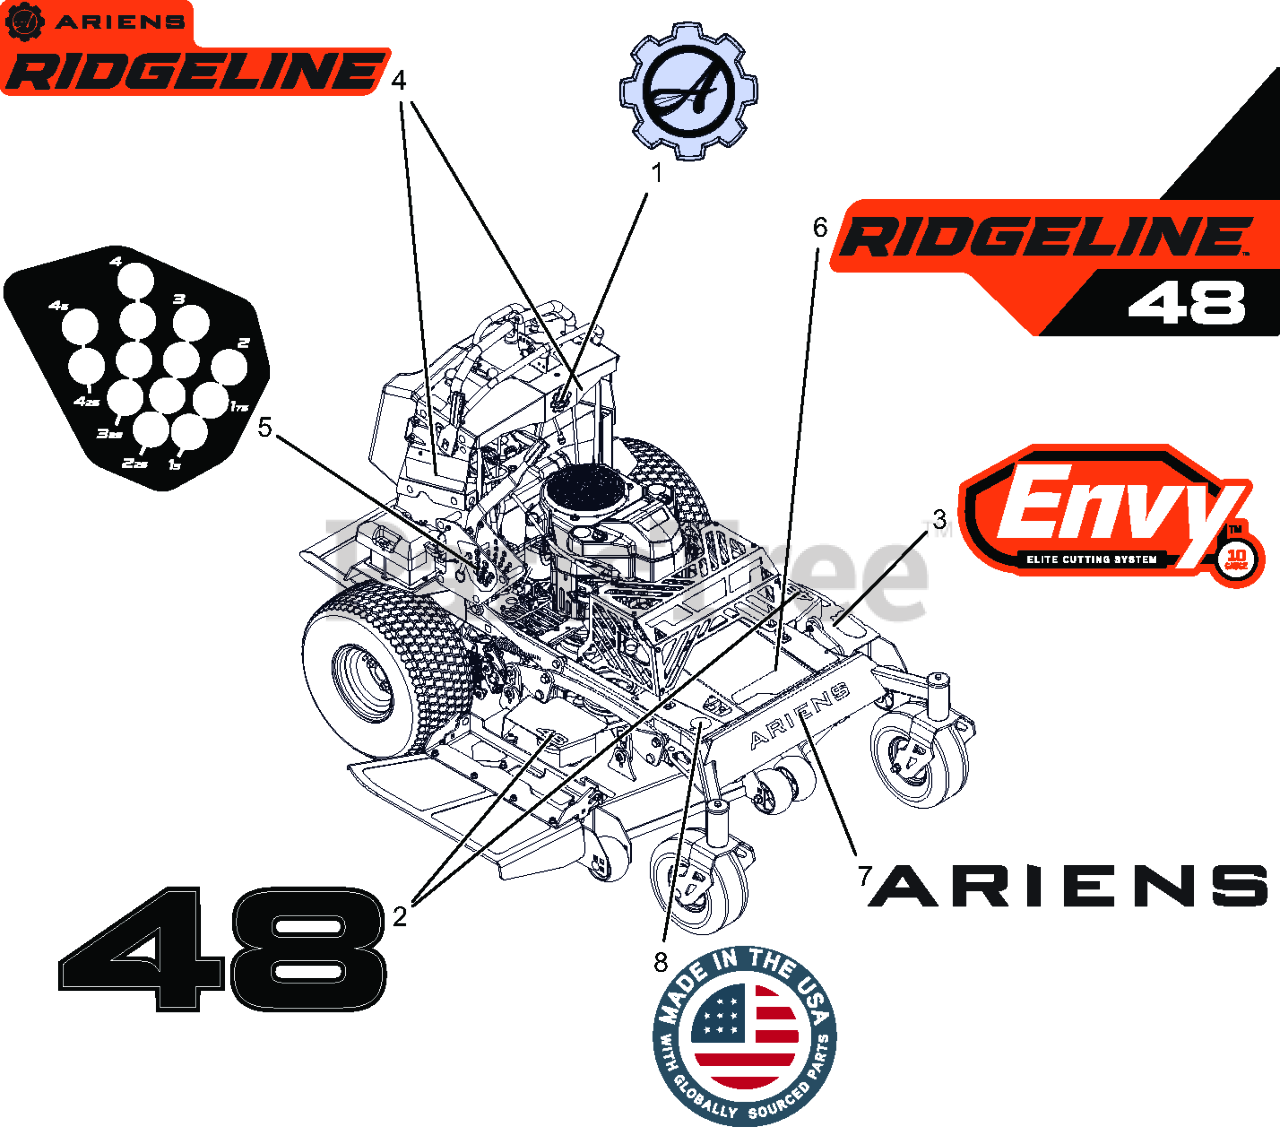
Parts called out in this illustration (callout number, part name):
1	DECAL- ARIENS GEAR BADGE
2	DECAL- DECK 48
3	DECAL- DECK -ENVY
4	DECAL- TOWER
5	DECAL- HOC
6	DECAL- RIDGELINE 48"
7	DECAL- ARIENS 15.0" BLACK
8	DECAL- MADE IN USA
